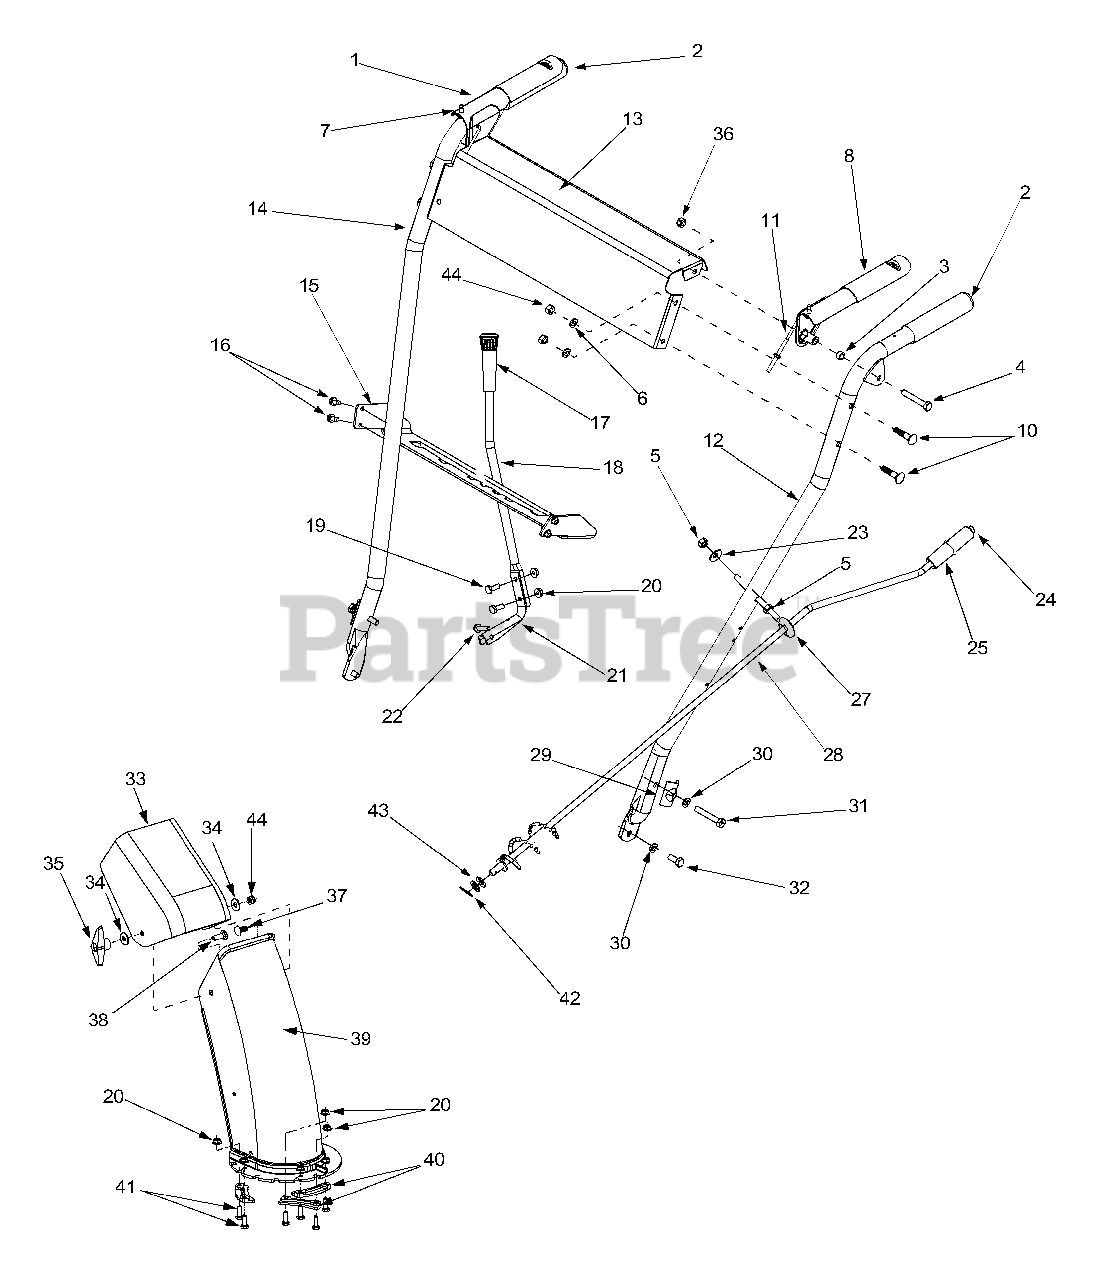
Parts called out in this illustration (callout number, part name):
1	Clutch Lever Assembly - RH
3	Spacer .325 ID x .460 OD
4	Hex Cap Screw 5/16 -18 x 2.0
5	Hex Nut 5/16-18
6	Lock Washer 5/16
7	Rubber Bumper
8	Clutch Lever Assembly - LH
10	Carriage Bolt 5/16-18 x 1.50
11	Z - Cable
16	Hex Washer Screw 1/4-20 x .50
19	Hex Cap Screw 1/4-20 x .75
20	Hex Lock Nut 1/4-20
21	Shift Lever Spring
22	Hex Washer Screw 1/4-20 x 1.0
23	Bell Washer
24	Push Cap
25	Chute Knob
27	Eyebolt
28	Chute Directional Control Assembly
29	Handle Tab
30	Lock Washer 5/16
31	Hex Cap Screw 5/16-18 x 1.75
32	Hex Cap Screw 5/16-18 x .75
33	Upper Chute
34	Washer 5/16
36	Hex Lock Nut 5/16-18
37	Carriage Bolt 5/16-18 x .75
38	Carriage Screw 5/16-18 x 1.0
39	Lower Chute
40	Flange Keeper
41	Hex Cap Screw 1/4-20 x .75
42	Cotter Pin
43	Flat Washer 3/8
44	Hex Patch Nut 5/16-18 Gr. 5
